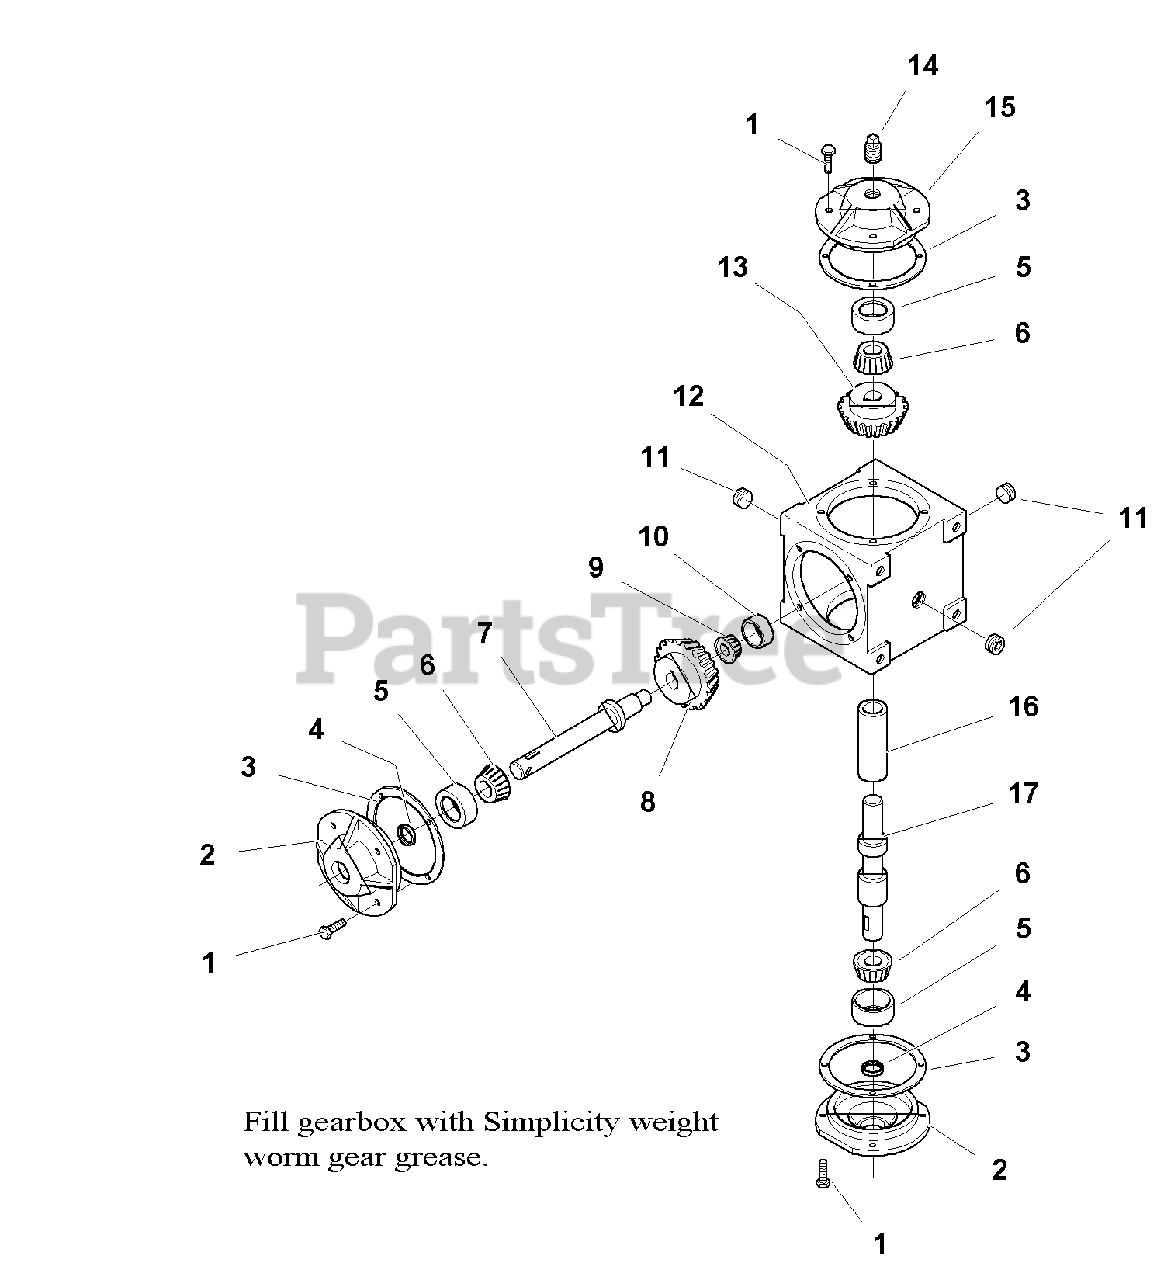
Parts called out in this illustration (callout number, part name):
1	CAPSCREW, Hex Head, Whiz Lock, 5/16-18 x 3/4
2	CAP (Not Serviced)
3	GASKET, 0.015
3	GASKET, 0.005
3	GASKET, 0.003
4	SEAL, Shaft, 1 x 1-1/2 x 5/16
5	BEARING, Cup
6	BEARING, Cone
7	SHAFT, Gearbox (Not Serviced)
9	BEARING, Cone
10	BEARING, Cup
11	PLUG, Pipe, Hex Socket Head
12	HOUSING, Gearbox
13	GEAR (Used with Rev. 1 & 2 Only)
13	GEAR (Used with Rev. 3 Only)
14	PLUG, Pipe, Sqr Head (Used with Rev. 3 Only)
15	CAP, Blank
16	SPACER, Gearbox (Used with Rev. 1 & 2 Only)
17	SHAFT (Used with Rev. 1 & 2 Only)
17	SHAFT (Used with Rev. 3 )
